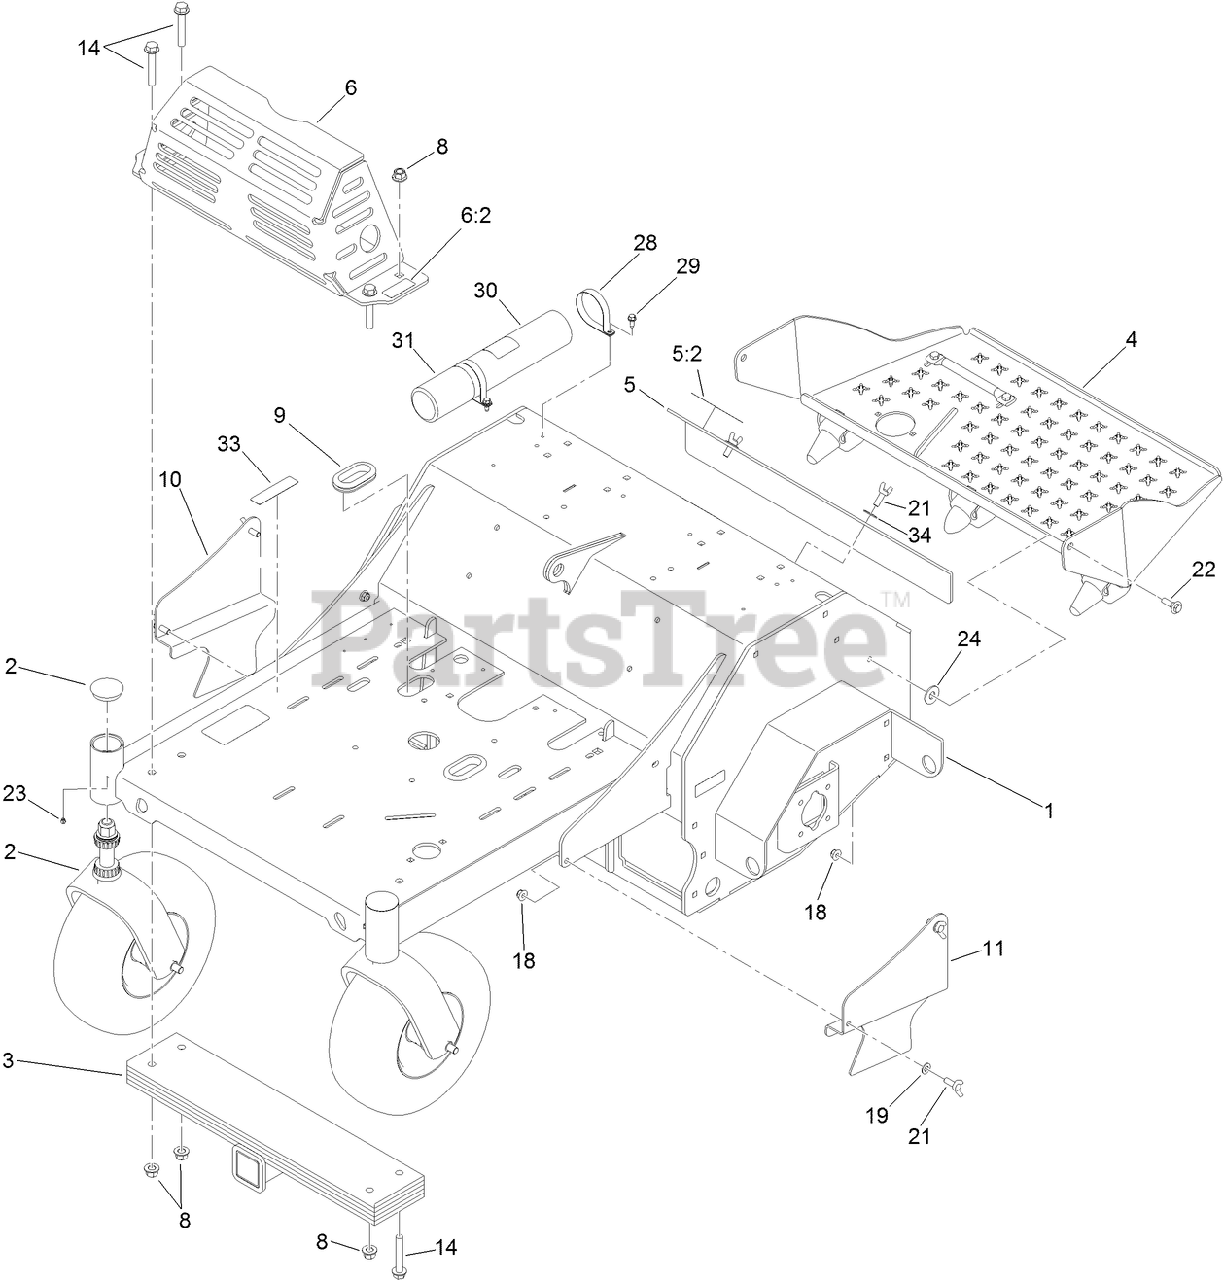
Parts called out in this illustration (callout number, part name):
1	MAIN FRAME ASM
2	FRONT CASTER ASM
4	PLATFORM W/ROCKER ASM
5	ACCESS COVER ASM
5:2	DECAL-OPERATION, TINE GROUND (CE)
6	MUFFLER GUARD ASM
6:2	DECAL-SURFACE, HOT
8	NUT-LOCK
9	GROMMET
10	GUARD-CHAIN, RH
11	GUARD-CHAIN, LH
14	SCREW-HF
18	NUT-HF, NI
19	WASHER-FLAT
21	SCREW-THUMB
22	SCREW-SHOULDER, HWH
24	WASHER-FLAT
28	R-Clamp
29	SCREW-HWH
30	TUBE-MANUAL
31	CAP-HOUSING
33	DECAL-ARRESTER, SPARK
34	WASHER-SPRING
